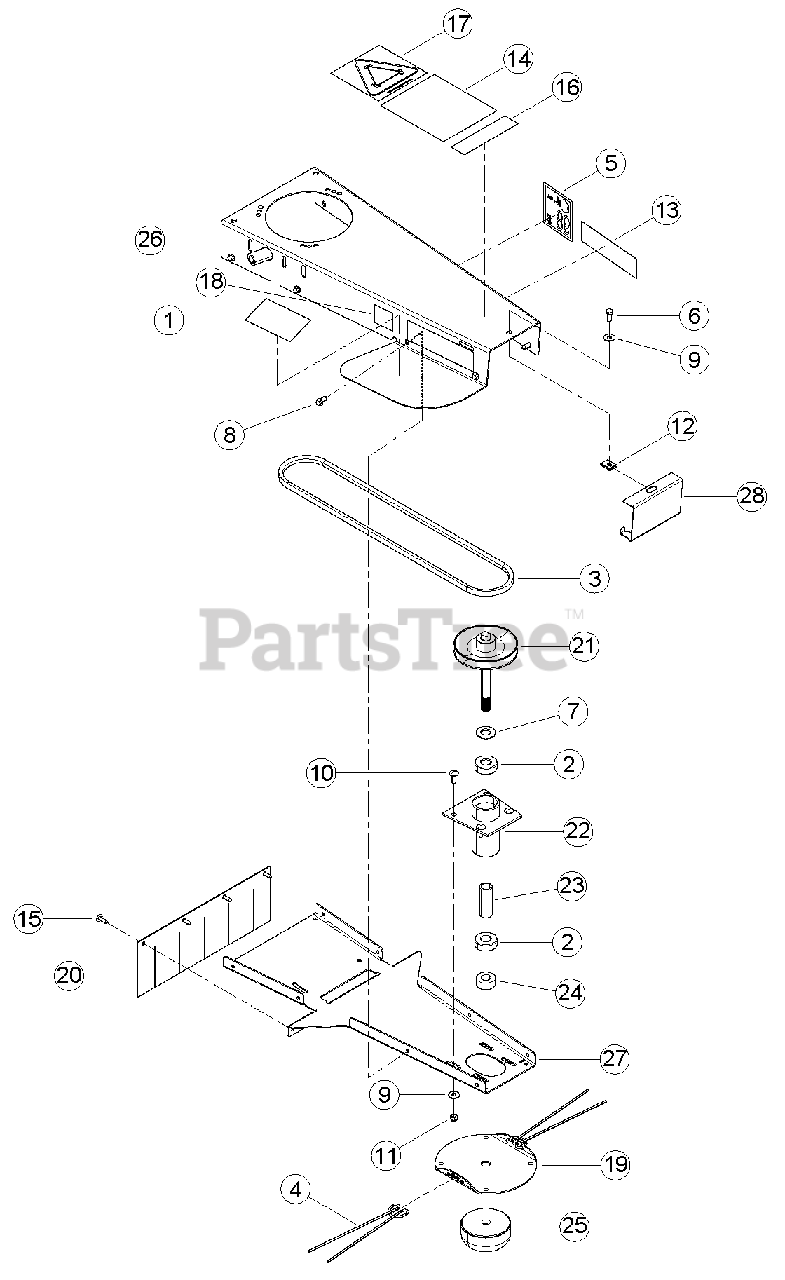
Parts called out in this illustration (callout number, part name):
1	DECAL, GRINDER DANGER
2	BEARING, 3/4 BALL
3	BELT, 4L 53 ARAMID
4	STRING, .155 X 20-1/2
5	DECAL, 98 DB (WT160TXS MODEL)
5	DECAL, 101 DB (WT190TXS MODEL)
6	BOLT, 5/16 X 3/4 HEX HD GR5 ZP
7	WASHER, 3/4 SAE FLAT ZP
8	SCREW, 11/32 X 7/8 HWH AB THREAD ZP
9	WASHER, 5/16 FLAT ZP
10	BOLT, 5/16 X 7/8 CRG GR5 NC ZP
11	NUT, 5/16 NE NYLOCK ZP
12	NUT, 5/16-18 TINNERMAN U-TYPE
13	DECAL, ECHO BEARCAT 6.82 X 1.90
14	DECAL, MANUAL/SAFETY INFO
15	RIVET, PLASTIC 1/4 X 7/8
16	DECAL, MODEL WT160T
16	DECAL, MODEL WT190T
17	DECAL, RECLAIM IT
18	DECAL, ECHO BEAR CAT QR CODE
19	DISK, TRIMMER HEAD
20	FLAP, TRIMMER
21	WELDMENT, TRIMMER PULLEY
22	WELDMENT, SPINDLE HUB
23	SPACER, TRIMMER SPINDLE
24	SPACER, TRIMMER HEAD
26	WELDMENT, TRIMMER BODY
27	BOTTOM, TRIMMER FRAME
28	COVER, FRONT TRIMMER
